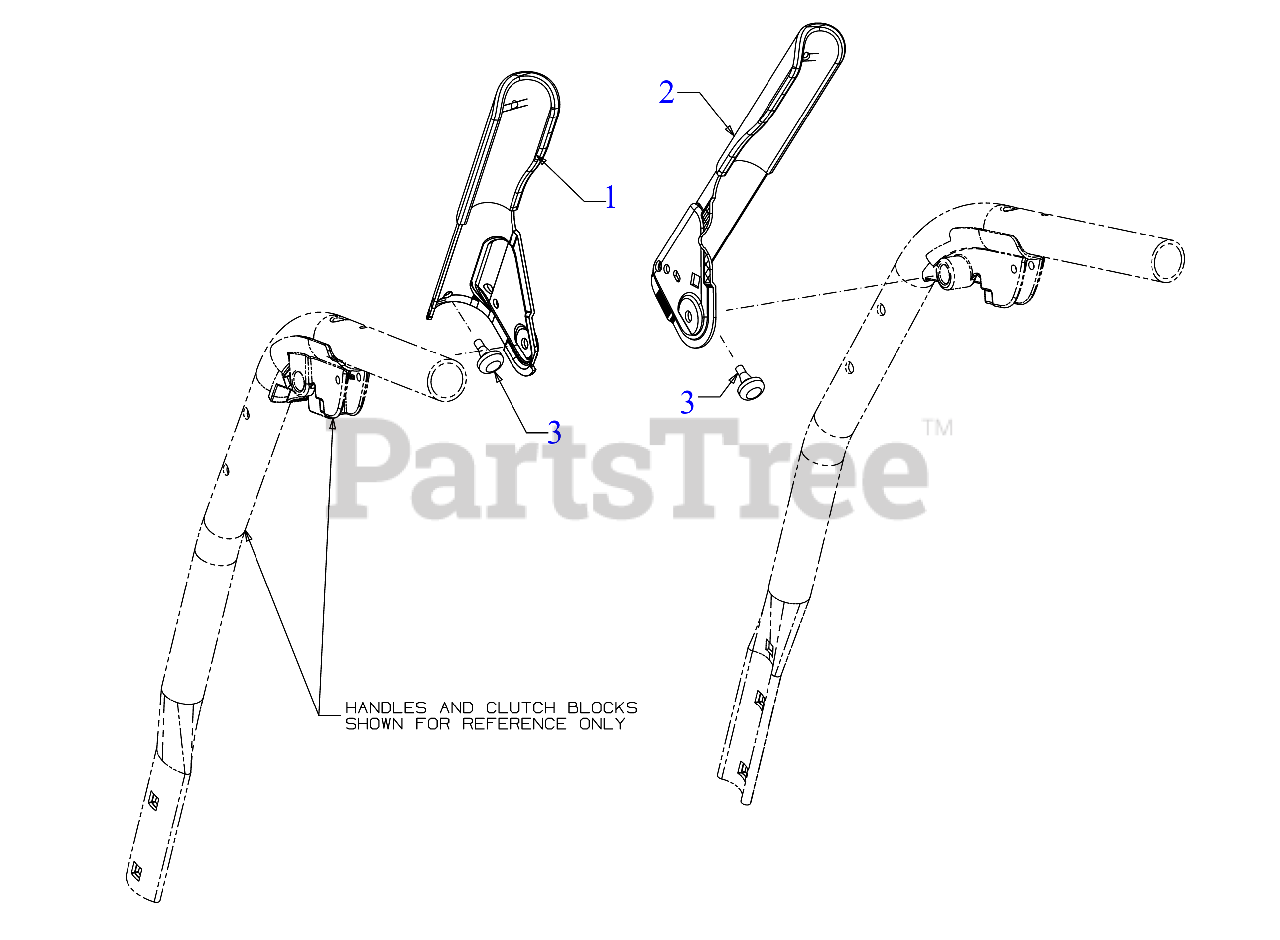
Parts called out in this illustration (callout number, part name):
1	HANDLE ASSEMBLY (LH)
2	ENGAGEMENT HANDLE ASSEMBLY (RH) (RED)
3	RUBBER BUMPER
